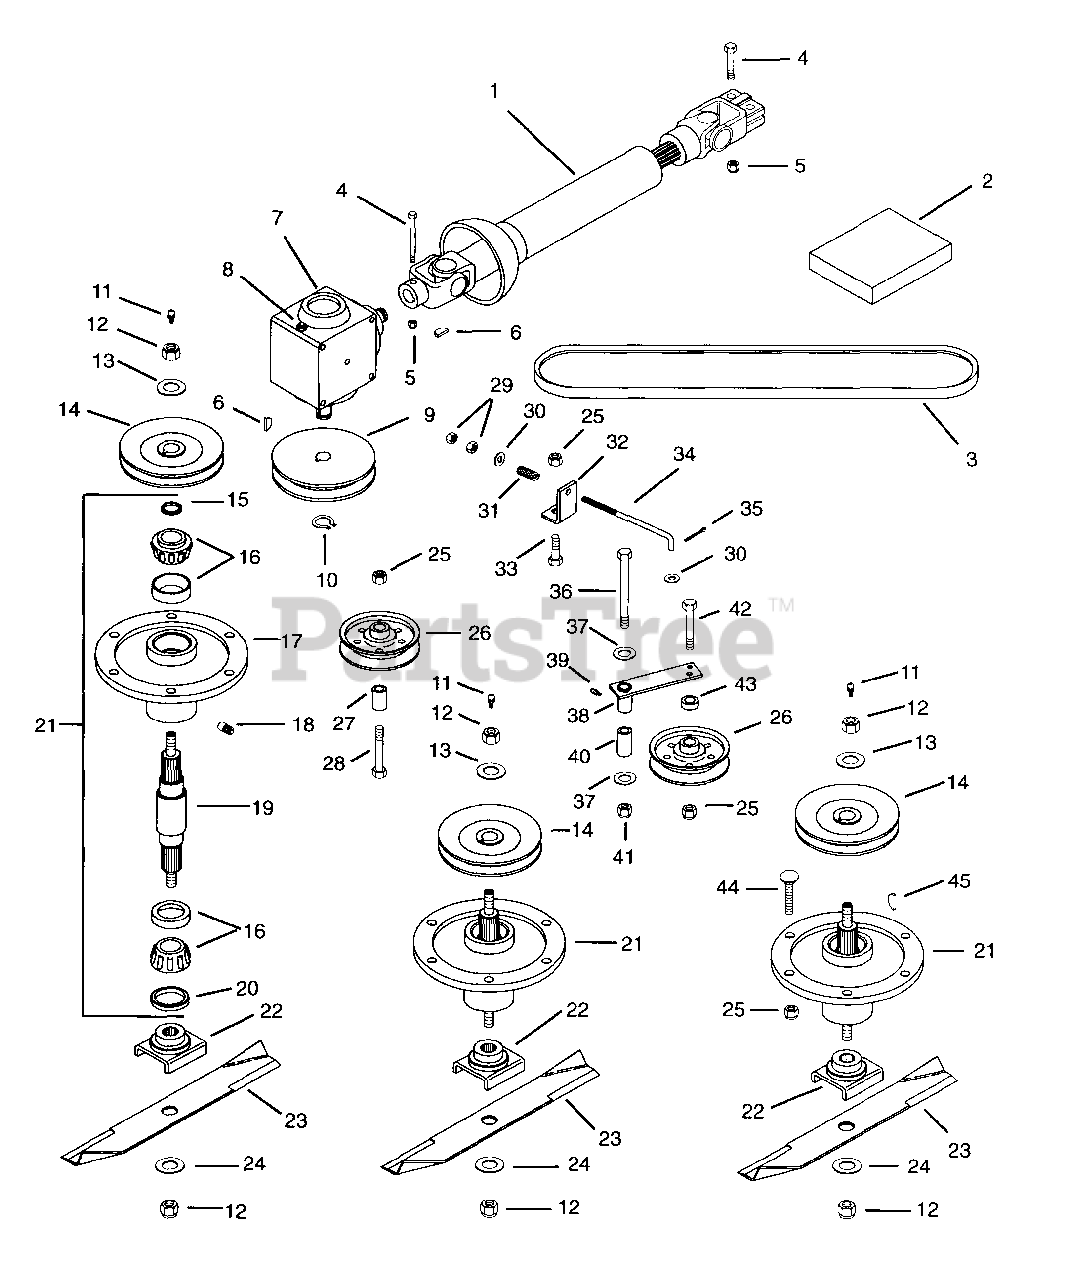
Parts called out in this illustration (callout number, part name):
1	Universal Joint Assembly
2	Kit, Repair U-Joint
3	V-Belt A-Section
4	Bolt-Hex .31-18 x 2.25 Grade 5
5	Nut-Locking-Nylon .312-18 Grade 2
6	Key-Woodruff .25 x .88
7	Gear Box, Right Angle
8	Plug, 1/8 Vent
9	Sheave, Mower Gearbox
10	Ring-Retaining-External .821 x .078
11	Fitting-Lube 1/8
12	Nut-Hex .625-11 Grade 2
13	Washer-Flat-Steel .687 x 1.312 x .150
14	Sheave
15	Seal 1.987 x 1.500 x .313
16	Assembly, Bearing Cup & Cone
17	Bearing Housing
18	Relief Fitting
19	Shaft, Spindle
20	Seal, 1.206 x 1.785 x .468
21	Service Kit Spindle Assembly
22	Weldment Blade Cradle
23	Blade, Mulching 50" Mower
24	Washer-Flat-Steel .656 x 1.312 x .095
25	Nut-Locking-Nylon .375-16 Grade 2
26	Pulley-Idler 4.50 x .380
27	Bushing-Sleeve .407 x .625 x .750
28	Bolt-Hex.38-16 x 2.50 Grade 5
29	Nut-Hex .375-24 Grade 2
30	Washer-Flat-Steel .406 x .812 x .062
31	Spring-Compression .125 x .78 x 1.00
32	Support, Spring
33	Bolt-Hex .38-16 x 1.00 Grade 5
34	Rod, Idler
35	Pin-Cotter .09 x .75
36	Bolt-Hex .50-13 x 3.375
37	Washer-Flat-Steel .500 x 1.250 x .083
38	Weldment, Idler Pivot
39	Fitting-Lube .25-28 x .256
40	Spacer .505 x.855 x 2.50
41	Nut-Locking .50-13 Grade 5
42	Bolt-Hex .38 x 1.75 Grade 5
43	Spacer .516 x .875 x .300
44	Bolt-Round Head Square Neck .38-16 x 1.50
45	Key-Woodruff .25 x 1
